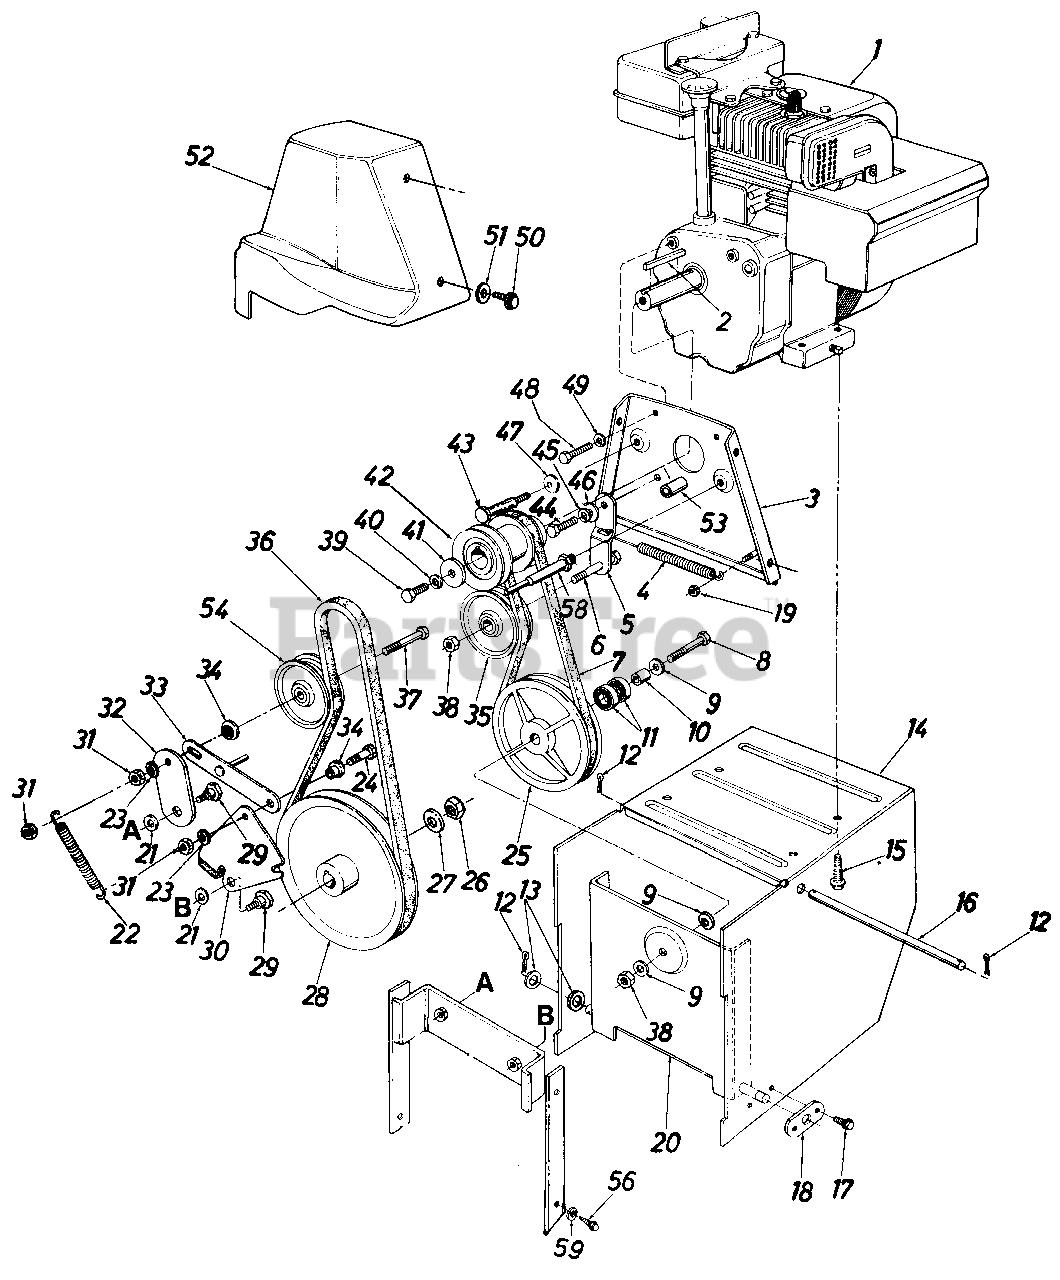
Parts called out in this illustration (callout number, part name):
1	Engine
2	Sq. Key 3/16" x 1.50" Lg.
3	Engine Plate Ass'y.
4	Extension Spring 50" O.D. x 3 97" Lg.
5	Drive Clutch Idler Brkt.
6	Hex Bolt 3/8-24 x 1.25" Lg.
7	"V"-Belt
8	Hex Bolt 3/8-24 x 1.50" Lg.
9	Bell-Wash. .40" I.D. x .88" O.D. x .06
10	Spacer .38" I.D. x .62" O.D. x 75" Lg
11	Ball Brg. .62" l.D. x 1.38" O.D. x .44
12	Cotter Pin 3/32" Dia. x 75" Lg.
13	Fl-Wash. .53" I.D. x 1.00" O.D. x .125
14	Frame Ass'y.
15	Hex Wash. Hd. Self-Tap Scr. 3/8-16 x 1.25" Lg.
16	Shaft .50" Dia. x 9.50" Lg.
17	Hex Wash. Hd. Self-Tap Scr. 1/4-20 x .50" Lg.
18	Axle Bracket
19	Hex L-Nut 1/4-20 Thd.
20	Drive Pulley Support Brkt. Ass'y.
21	Bell-Wash. .40" I.D. x 1.13" O.D.
22	Extension Spring .56" O.D. x 4" Lg.
23	L-Wash. 3/8" I.D.
24	Hex Scr. 3/8-16 x 1.25" Lg.
25	6.00" O.D. Drive Pulley Ass'y.
26	Hex Jam Cent. L-Nut 5/8-18 Thd.
27	Fl-Wash. .64" I.D. x .94" O.D. x .06
28	1/2" V-Pulley .625" I.D. x 7.50" O.D.
29	Shld. Bolt .625" Dia. x .170" Lg. (3/8-16)
30	Brake Bracket Ass'y.
31	Hex Ins. L-Nut 3/8-16 Thd.
32	Auger Clutch Idler Brkt.
33	Brake Linkage Ass'y.
34	Shld. Spacer .625" I.D.
35	Fl-ldler Pulley 2.25" O.D.
36	"V"-Belt
37	Hex Bolt 3/8-16 x 2" Lg.
38	Hex Ins. Jam L-Nut 3/8-24 Thd.
39	Hex Bolt 3/8-24 x 1.50" Lg.
40	L-Wash. 3/8" I.D.
41	Bell-Wash. .40" I.D. x 1.25" O.D.
42	Double Groove Engine Pulley
43	Shld. Scr. .498" x 3.0" Lg.
44	Hex Bolt 5/16-24 x 1.00" L
45	L-Wash. 5/16" l.D.
46	Shld. Spacer .27" Lg.
47	Bell-Wash. .40" I.D. x .88" x .06
48	Hex Bolt 5/16-24 x .62" Lg.
49	L-Wash. 5/16" l.D.
50	Hex Wash. Hd. Self-Tap Scr. 1/4-20 x .50" Lg.
51	Fl-Wash. .28" I.D. x .75" O.D. x .06
53	Spacer
54	Fl-ldler Pulley 2.75" O.D.
56	Hex Wash. Hd. Self-Tap Scr. 3/8-16 x .75" Lg.
58	Stud 3/8-16 x 3.37" Lg.
59	L-Wash. 818" l.D.-H.D.
